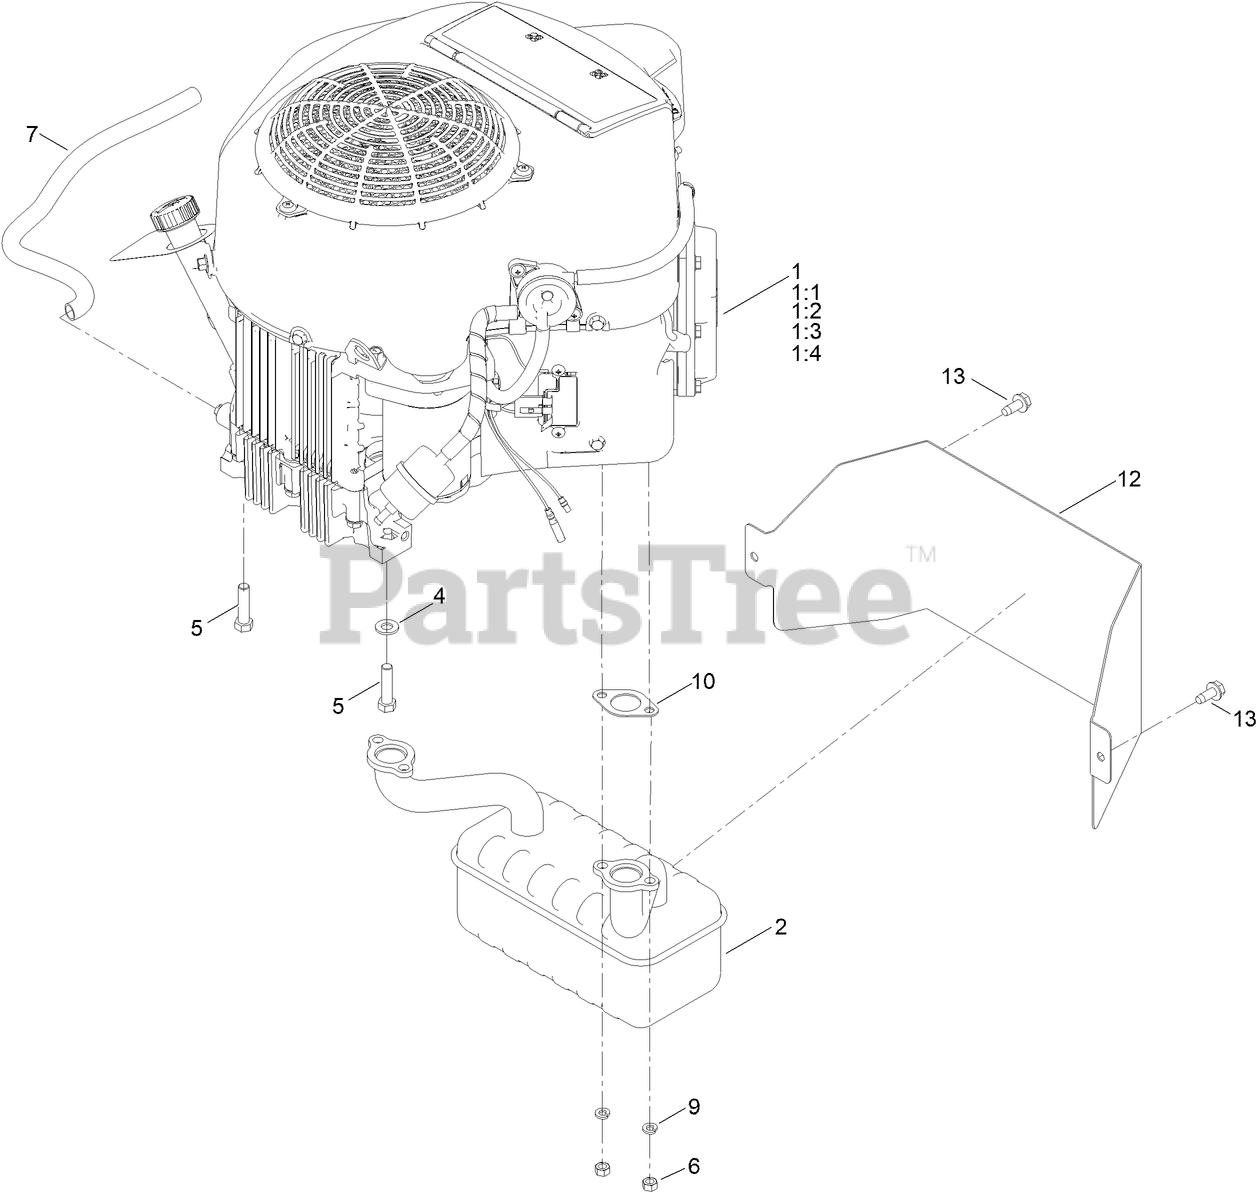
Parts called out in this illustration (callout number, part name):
1:1	KAWASAKI 49065-7007 ENGINE OIL FILTER
1:2	KAWASAKI 49019-7005 FUEL FILTER
1:4	KAWASAKI 11013-7049 ENGINE AIR FILTER
2	MUFFLER
4	WASHER-FLAT
5	BOLT-HH
7	TUBE-DRAIN, OIL
9	WASHER-LOCK
10	GASKET-EXHAUST
12	HEAT SHIELD - MUFFLER
13	SCREW-HWHTF
